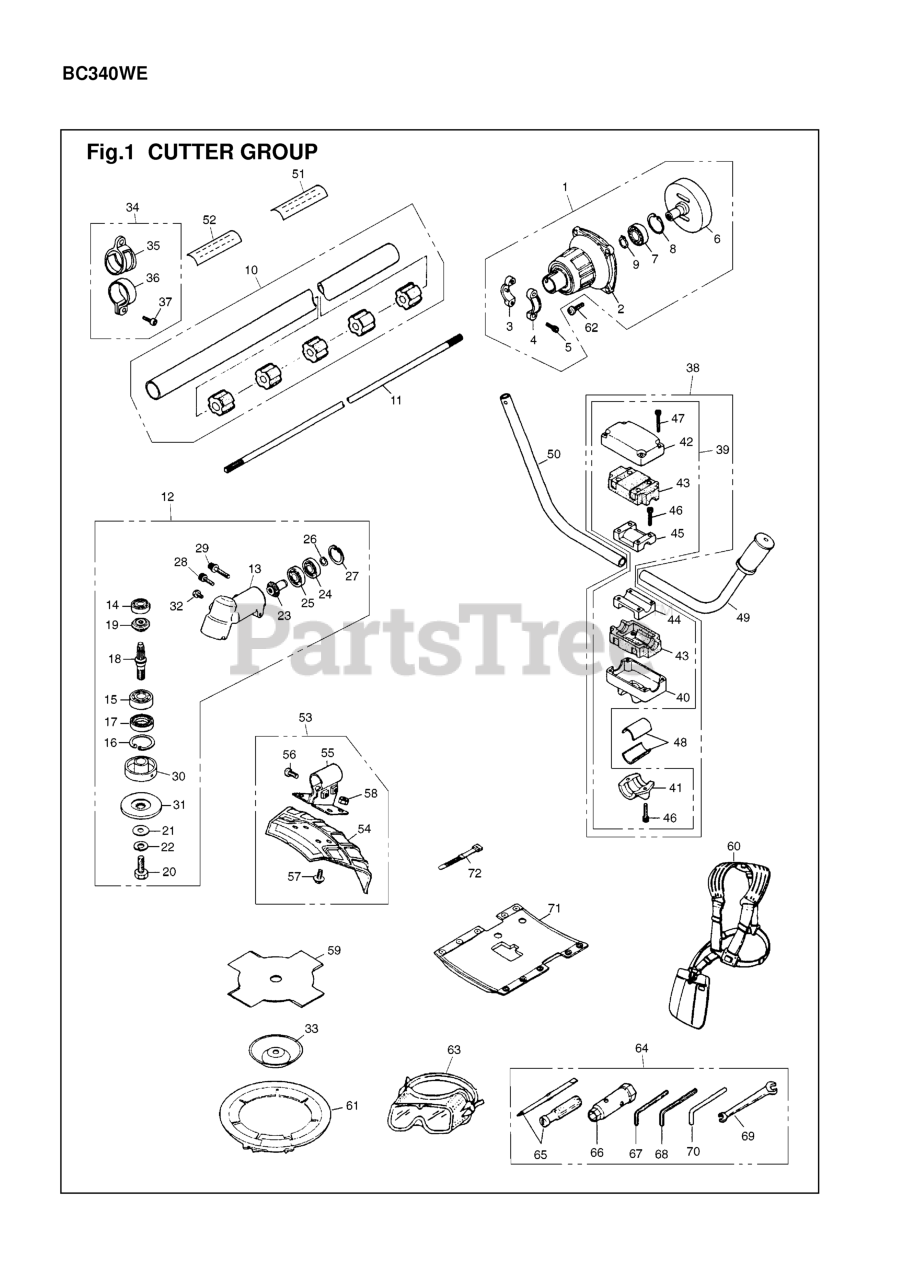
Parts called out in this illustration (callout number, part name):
1	HOUSING ASSY
2	HOUSING ASSY (RPLS-11100)
3	CLAMP, RIGHT (RPLS -11130)
4	CLAMP, LEFT (RPLS-11140)
5	BOLT
6	DRUM, CLUTCH
7	BEARING
8	SNAP RING
9	RING, SNAP, M15 X 1.0
10	PIPE COMP
12	GEARCASE ASSY
13	GEARCASE
14	BEARING
16	SNAP RING
17	SEAL
18	SHAFT
19	GEAR, BEVEL
20	BOLT
21	WASHER
22	WASHER
25	BEARING
26	RING, SNAP
27	SNAP RING
28	BOLT
29	BOLT
30	HOLDER (A)
31	HOLDER (B)
33	COVER
34	HANGER ASSY. (NLA)
35	HANGER
36	CLAMP
38	BRACKET ASSY
40	BRACKET (RPLS -14111)
43	ABSORBER
44	CLAMP (A)
45	CLAMP (B)
46	BOLT, M5 X 25
47	BOLT, M5 X 30
49	HANDLE L
51	PLATE, NAME
52	PLATE, CAUTION
53	GUARD ASSY
54	GUARD
60	HARNESS ASSEMBLY
61	COVER (REPLACES D0041) ACC.
62	BOLT, M6 x 20
64	TOOL SET
65	DRIVER
68	WRENCH (TOOL)
69	SPANNER
70	BAR
71	PROTECTOR (RPLS-17111)
72	BAND
